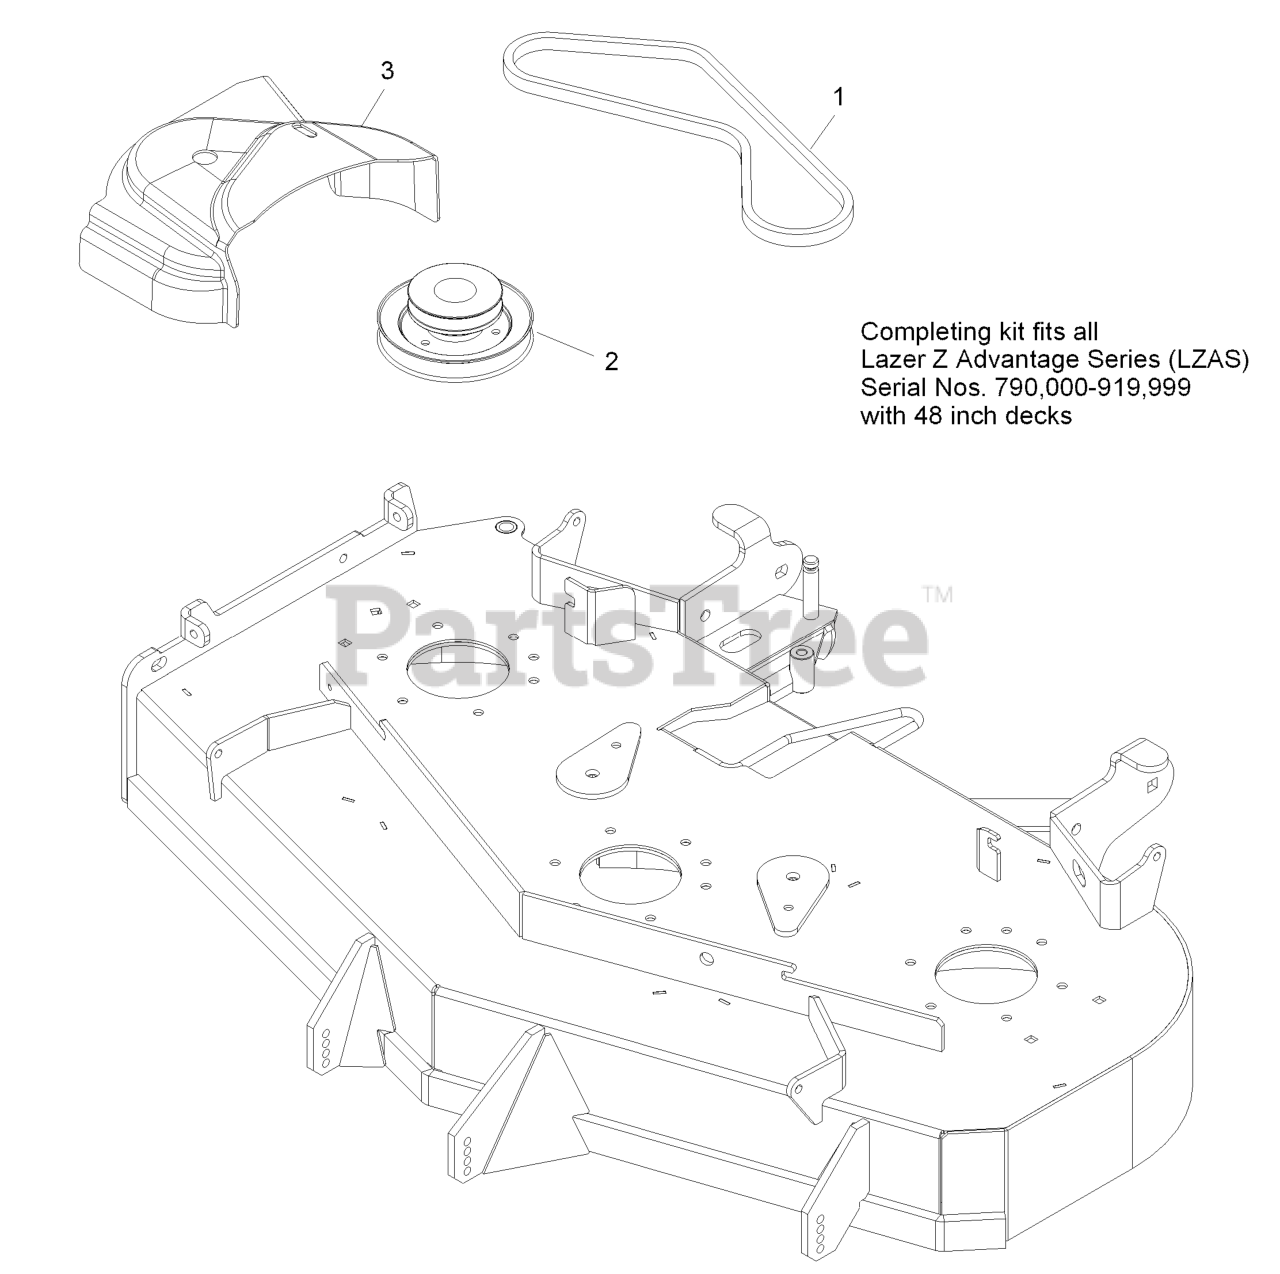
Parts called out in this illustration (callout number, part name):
1	BELT-BLOWER
2	JACKSHAFT,UV DRIVE 484
3	COVER,BELT UV 48
